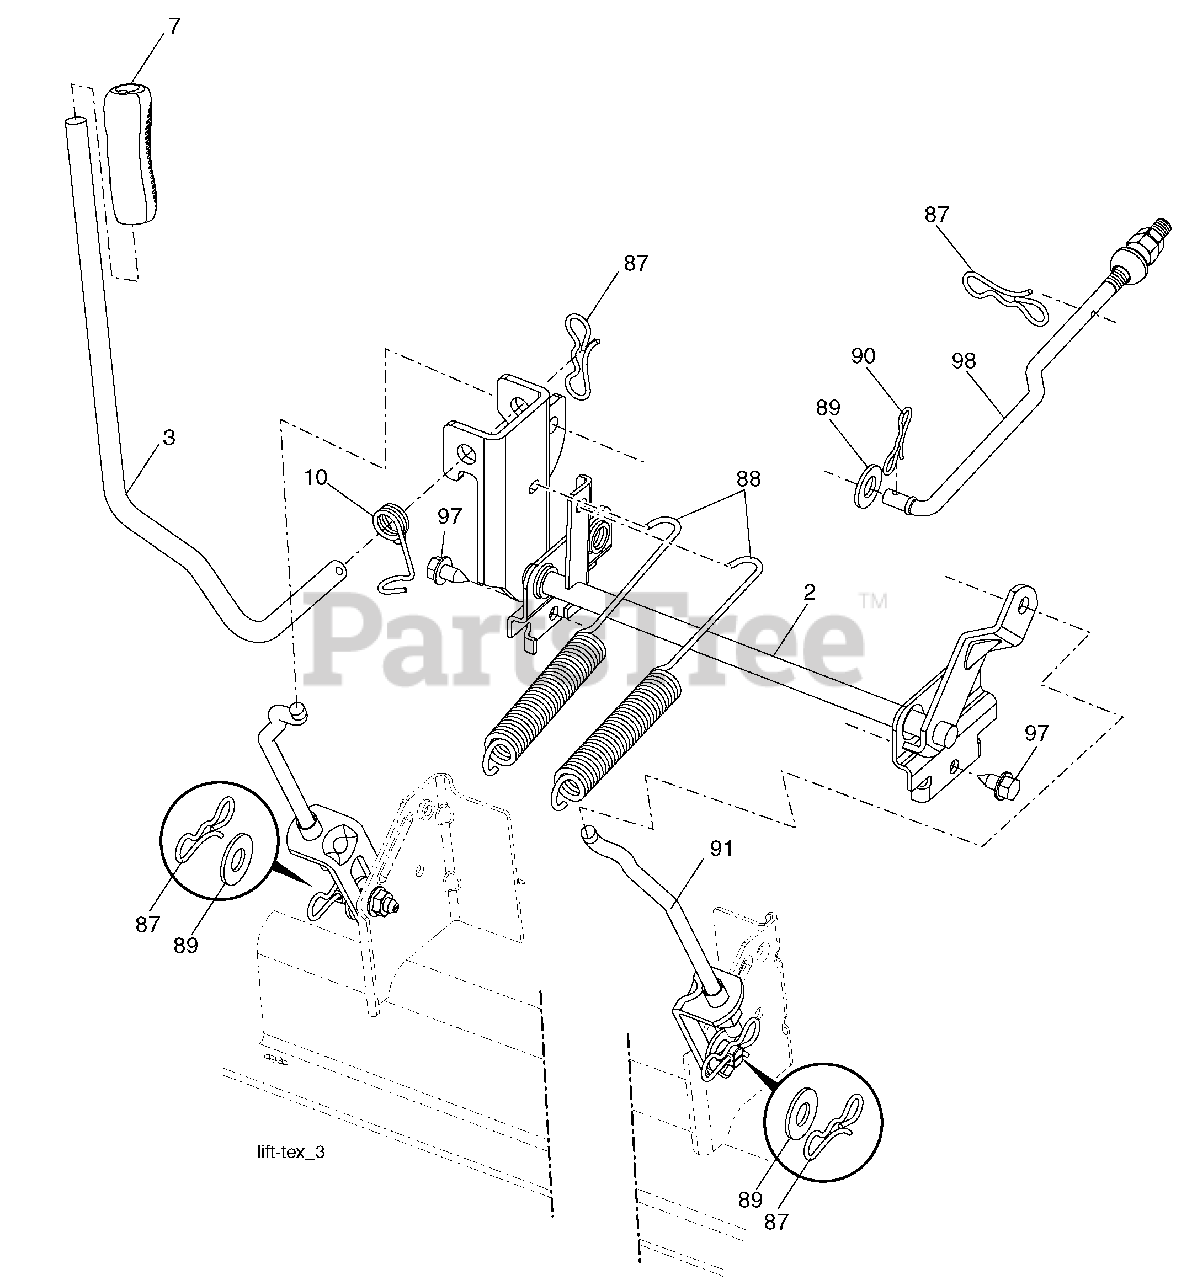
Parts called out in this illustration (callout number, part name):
2	Shaft Asm., Lift
3	Lever Asm., Lift Rh
7	Grip, Lever
10	Spring Torsion
87	Pin Cotter 7/16 Bow Tie Lock
88	Spring Lift Assist
89	Washer Clear Zinc
90	Pin Cotter 5/16 Bow Tie Lock
91	Link Lift Susp Mower Rear
92	Bracket Connect Link Lift
95	Bushing Alignment Link Lift
97	Screw 3/8-16 x .75 Smgml Tap/R.Z
98	Link Lift Susp. Front Mower
99	Bushing Spherical Susp Front
100	Nut Hex Jam ASF 7/16-20 unf
